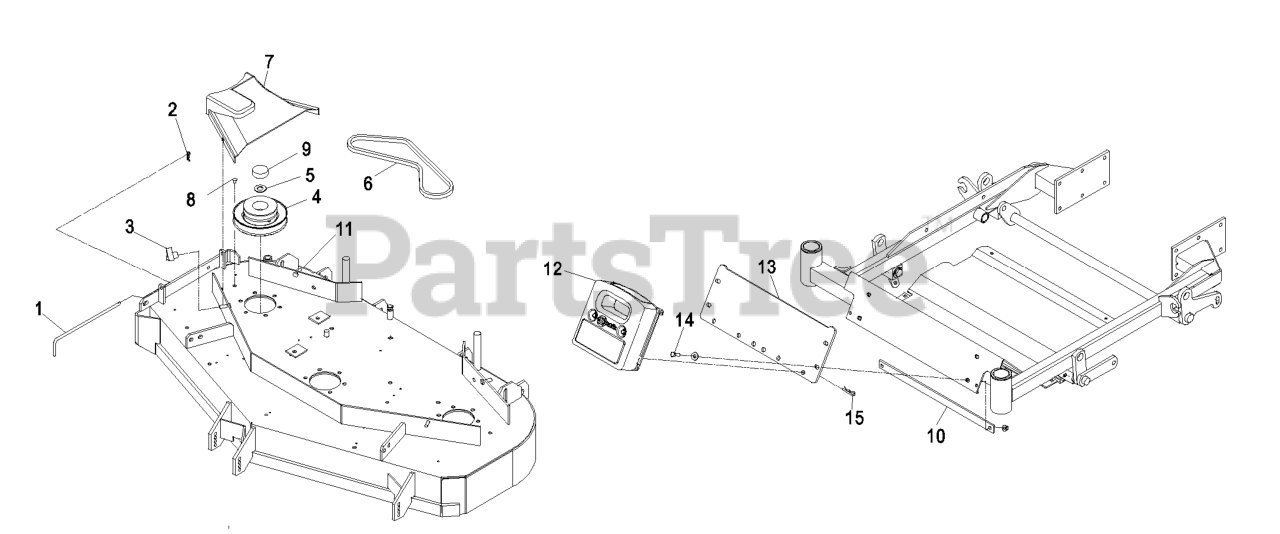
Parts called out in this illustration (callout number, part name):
1	PIN, CHUTE PIVOT
2	PIN-COTTER
3	KNOB-3 PRONG
4	SHEAVE, BLOWER DRIVE 50
5	WASHER-FLAT
6	BELT, BLOWER DRIVE 60
7	COVER, BELT 50
8	SCREW-HH
9	PLUG, BLACK NYLON 1.75
10	STRAP,WEIGHT MOUNT
11	BOLT-CARR
12	ASM,CAST WEIGHT
13	PLATE,WEIGHT ASM MOUNT
14	SCREW-HH
15	PIN-HAIR
